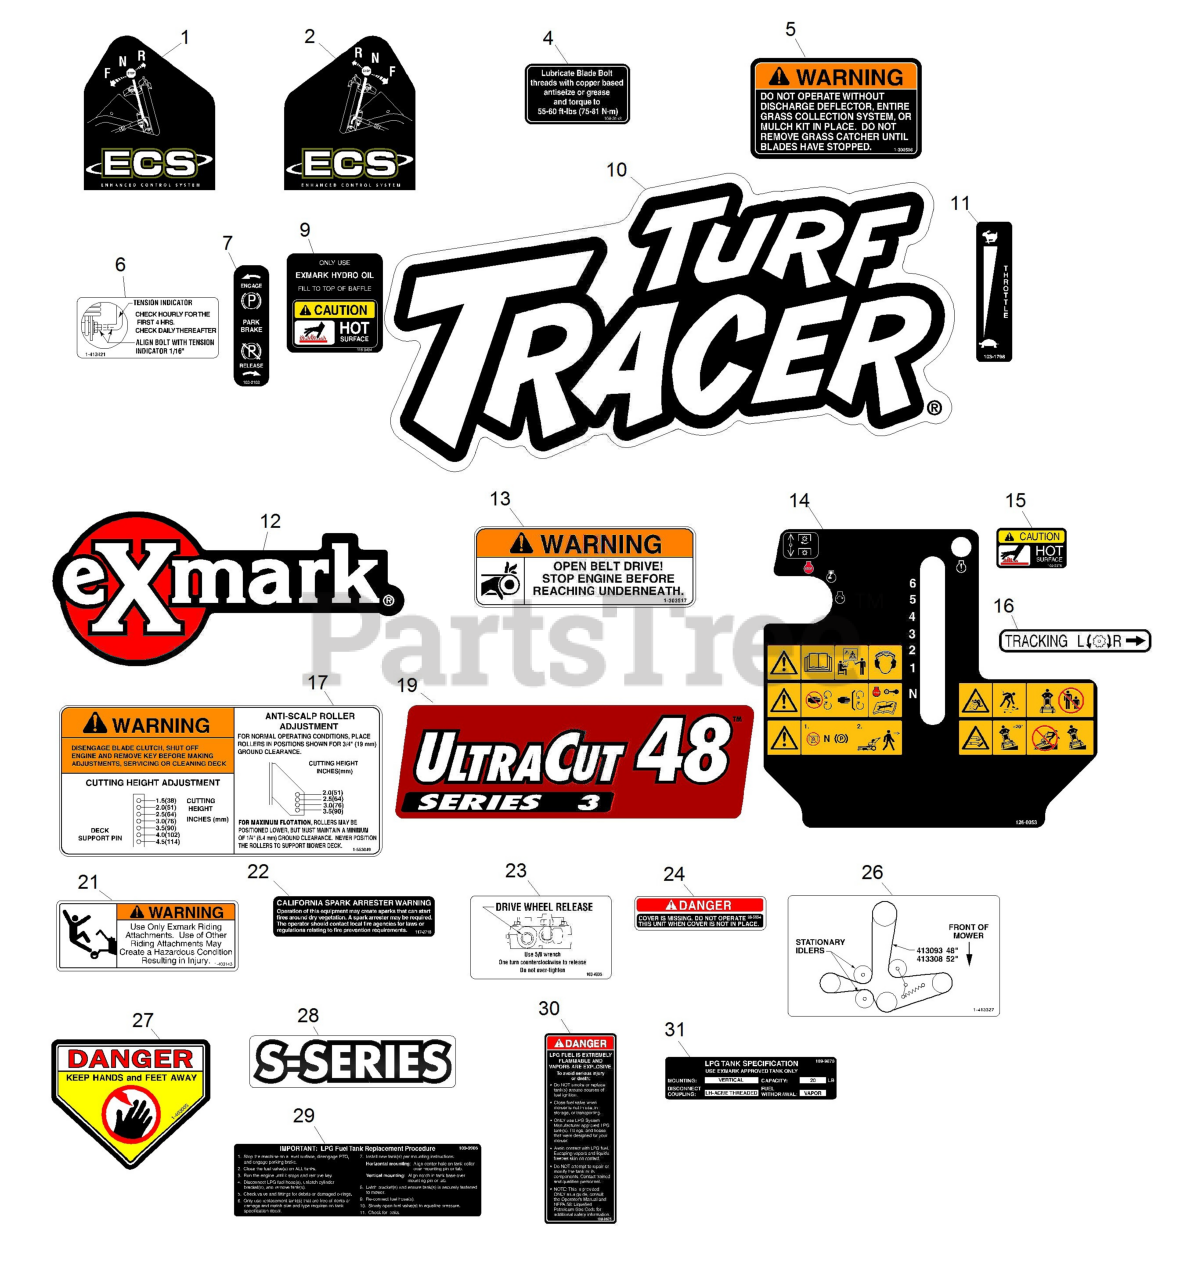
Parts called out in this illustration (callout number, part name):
1	DECAL,LH ECS INSTRUCTION
2	DECAL,RH ECS INSTRUCTION
4	DECAL,BOLT TORQUE
5	DECAL-WARNING, DISCHARGE
6	DECAL,INDICATOR
7	DECAL-BRAKE, PARK
9	DECAL-HYDRAULIC TANK
10	DECAL,TTH MODEL
11	DECAL,THROTTLE ONLY
12	DECAL,EXMARK LOGO
13	DECAL,BELT DRIVE
14	DECAL, CONSOLE TTS EFI
15	DECAL-CAUTION
16	DECAL,TRACKING ADJUST
17	DECAL,ANTI SCALP
19	DECAL-ULTRACUT 48 SERIES
21	DECAL,SULKY WARNING
22	DECAL-ARRESTER, SPARK
23	DECAL,DRIVE RELEASE
24	DECAL-COVER, MISSING
26	DECAL,BELT ROUTING
27	DECAL-DANGER
28	DECAL-S-SERIES
29	DECAL-TANK REPLACEMENT
30	DECAL-LPG WARNING
31	DECAL,LPG TANK SPEC VERTI
